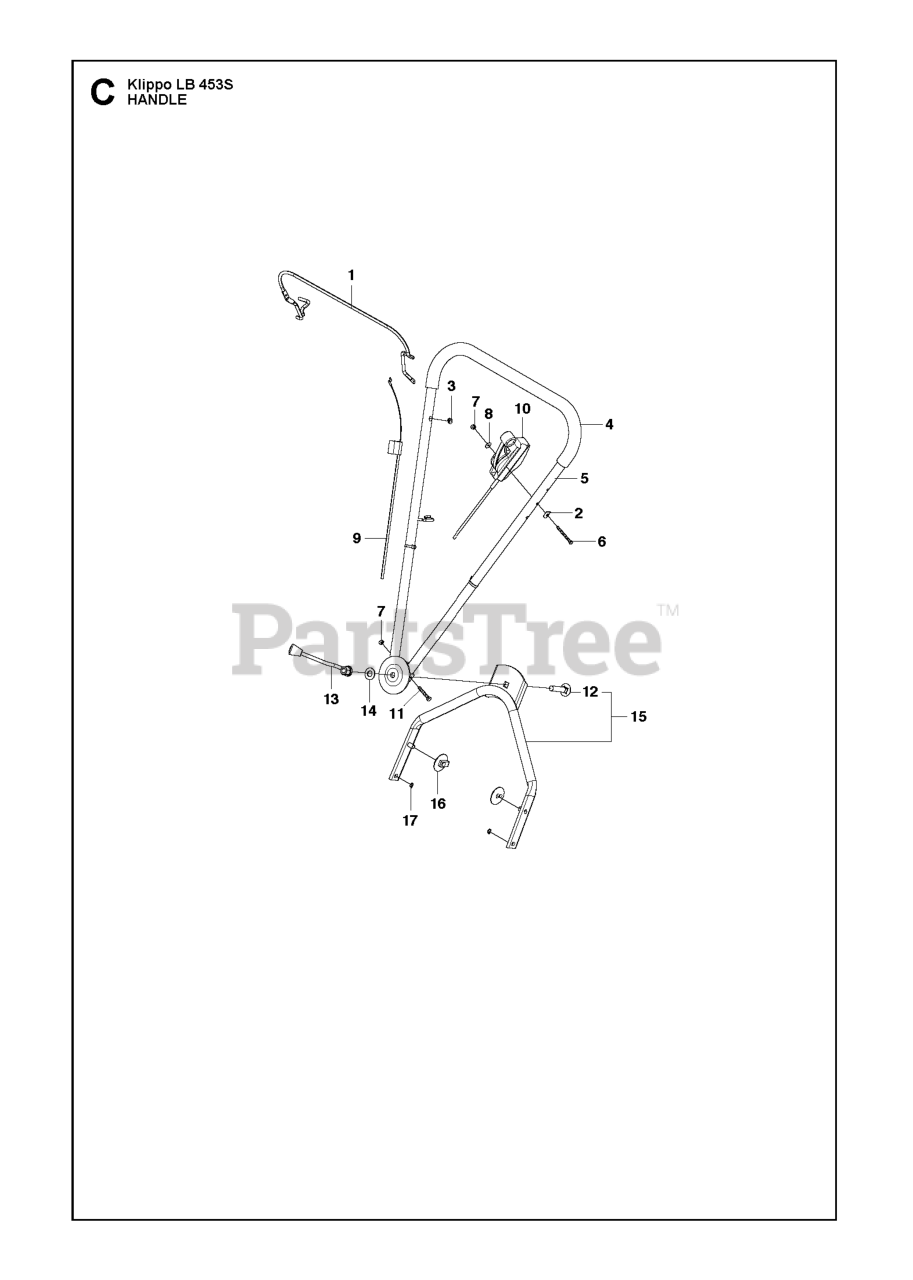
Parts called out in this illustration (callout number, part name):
1	Duo-Bal Harness
1	Harness
4	RP CLIP
5	FRONT PIECE
6	FRONT PIECE
8	HARNESS HOOK, COMPLETE
9	CATCH *
10	SPRING
11	HOOK
